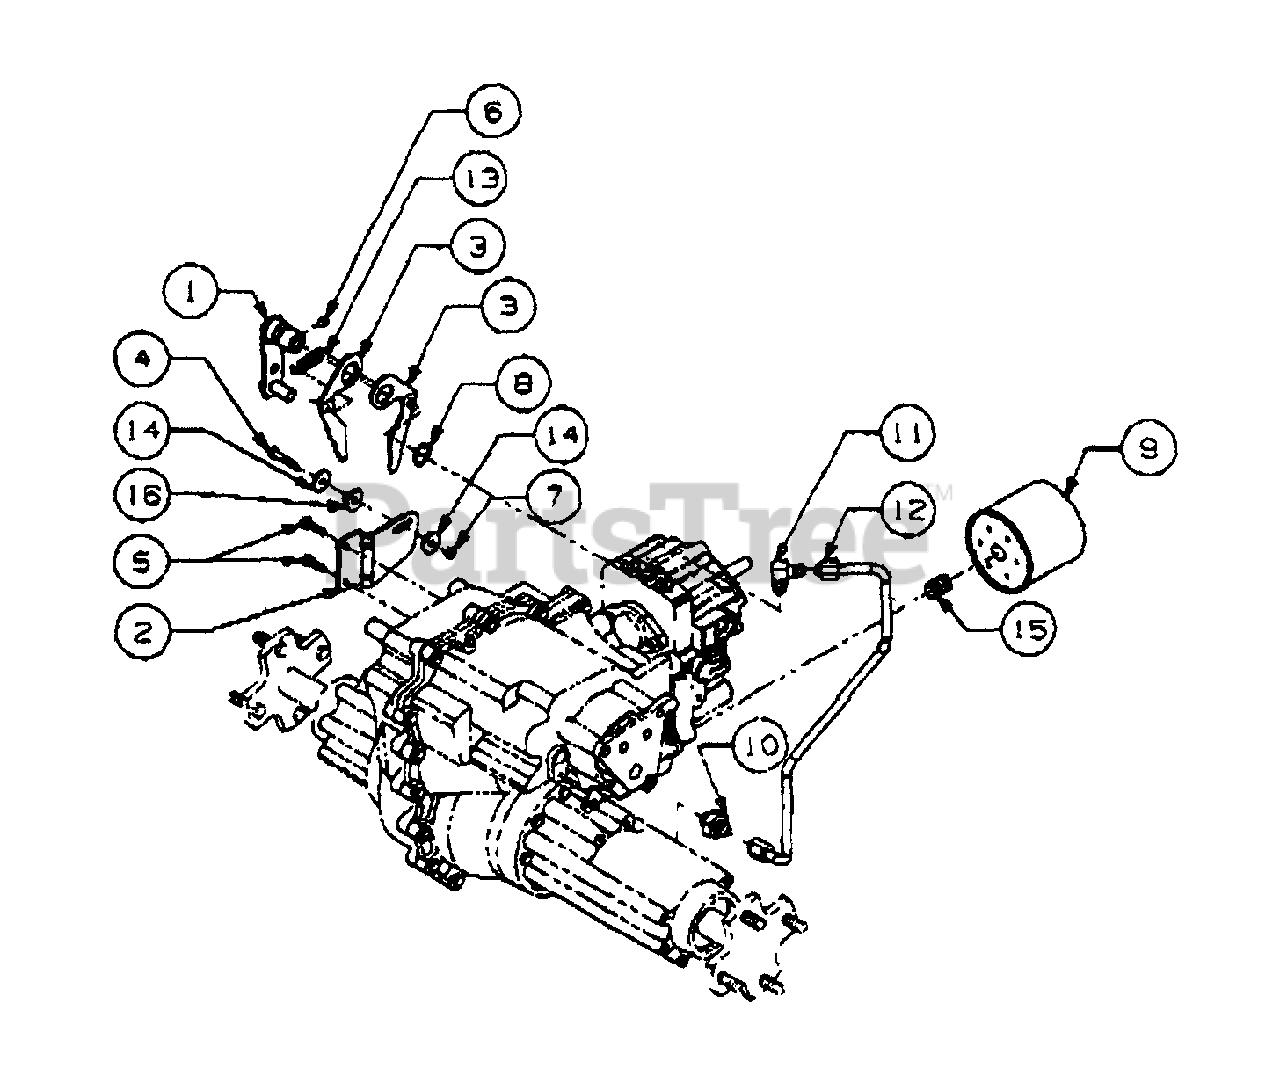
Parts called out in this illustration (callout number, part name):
1	Arm Assy, Control
2	Bracket, Hydro Neutral
3	Arm, Neutral
4	Screw, Hex Cap, 1/4-20 x 1.25 Lg
5	Screw, Hex Wash TT-Tap, 1/4-20 x 1.0 Lg
6	Screw w/Patch,Set
7	Nut, Hex Top Lock, 1/4-20
8	Ring, Snap, .875 Shaft
9	Filter, Oil
10	Connector, Tube 37 Deg w/O-Ring
11	Elbow, Adjustable w/O-Ring
12	Tube, Pickup
13	Spring, Extension, .50 OD x 1.97 Lg
14	Washer, Flat, .25 x .93 x .120 Thk
15	Nipple, Oil Filter
16	Spacer, Centering
